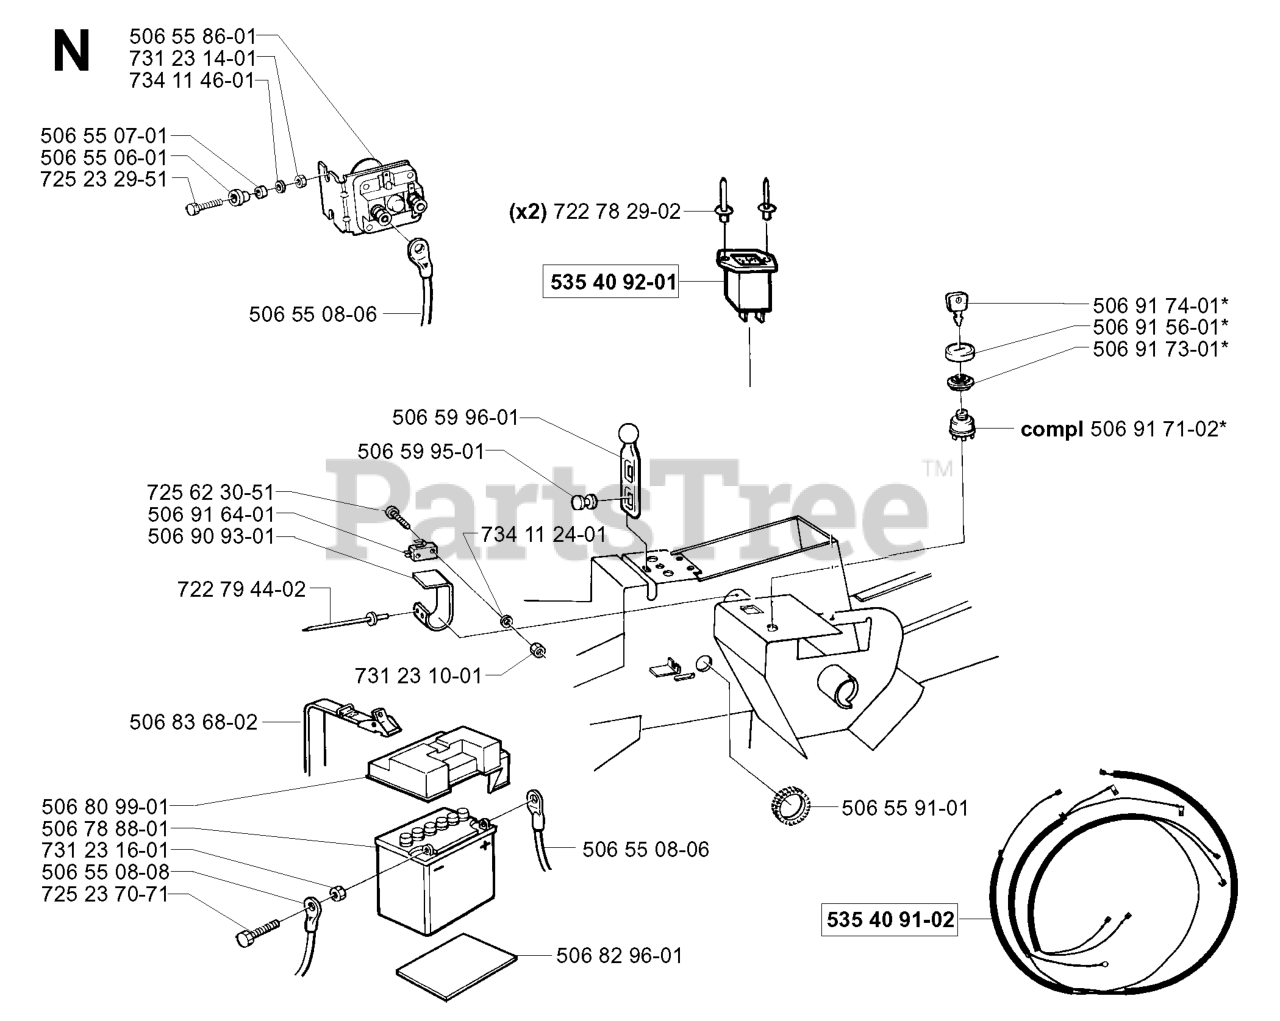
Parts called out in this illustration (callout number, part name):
1	CHASSIS STAMPING
2	DRAWBAR, 12GA
5	BUMPER.RUBBER.HOOD
9	DASH
10	BOLT D
11	PANEL.DASH.LH.LTX
13	PANEL DASH RH
14	SCREW LT
18	BUMPER.HOOD.LARGE.1.75"
26	NUT
30	FENDER FOOTREST
31	BRACKET.SUPPORT.FENDER
37	Screw 5/16-18 x 1/2 Hex, Self Tapping 5/16-18 x 1/2
38	BRACKET.ASM.PIVOT.MOWER.REAR
39	BRACKET PIVOT LASER
60	Bolt - Rd. Hd. Sq. Neckiage 3/8 16 x 3/4
64	DASH LOWER
142	PLATE REINFORCEMENT
143	BRACKET, SWAYBAR CHASSIS
144	BRKT, FOOT REST
145	ROD PIVOT CHASSIS/HOOD
166	SCREW
206	SHOULDER BOLT 5/16-18TT
207	SCREW, 5/16-18 X 1/2
208	SCREW 3/8-16X1/2
209	SCREW, 3/8-16X3/4
212	INSERT.LENS.REFLECTIVE
258	LENS LH
259	LENS LH
260	COVER.LENS.HUSQ.( HAVE GRAY)
261	INSERT GRILLE
